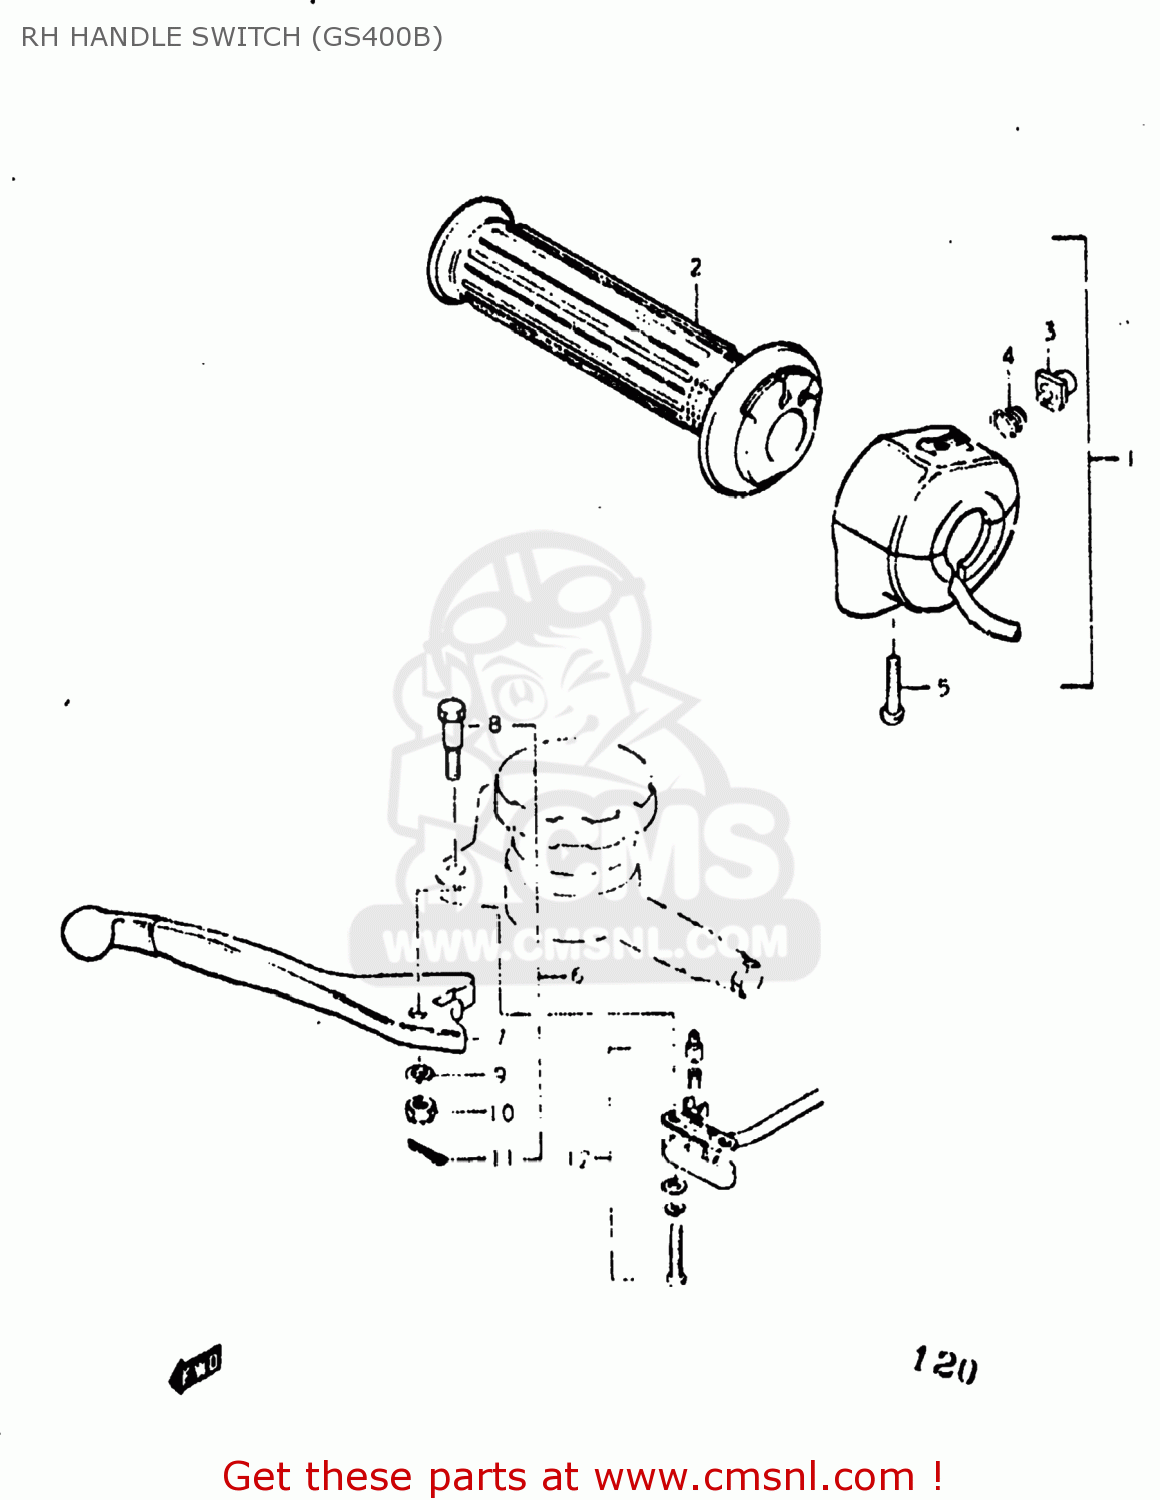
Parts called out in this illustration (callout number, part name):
1	GRIP ASSEMBLY,THROTTLE
2	GRIP,THROTTLE
3	BUTTON
4	SPRING
5	SCREW
6	LEVER ASSEMBLY,BRAKE
7	LEVER,BRAKE
8	BOLT,LEVER
9	LOCK WASHER
10	NUT,LEVER FITTNG
11	COTTER PIN
12	SWITCH ASSY,STOP
